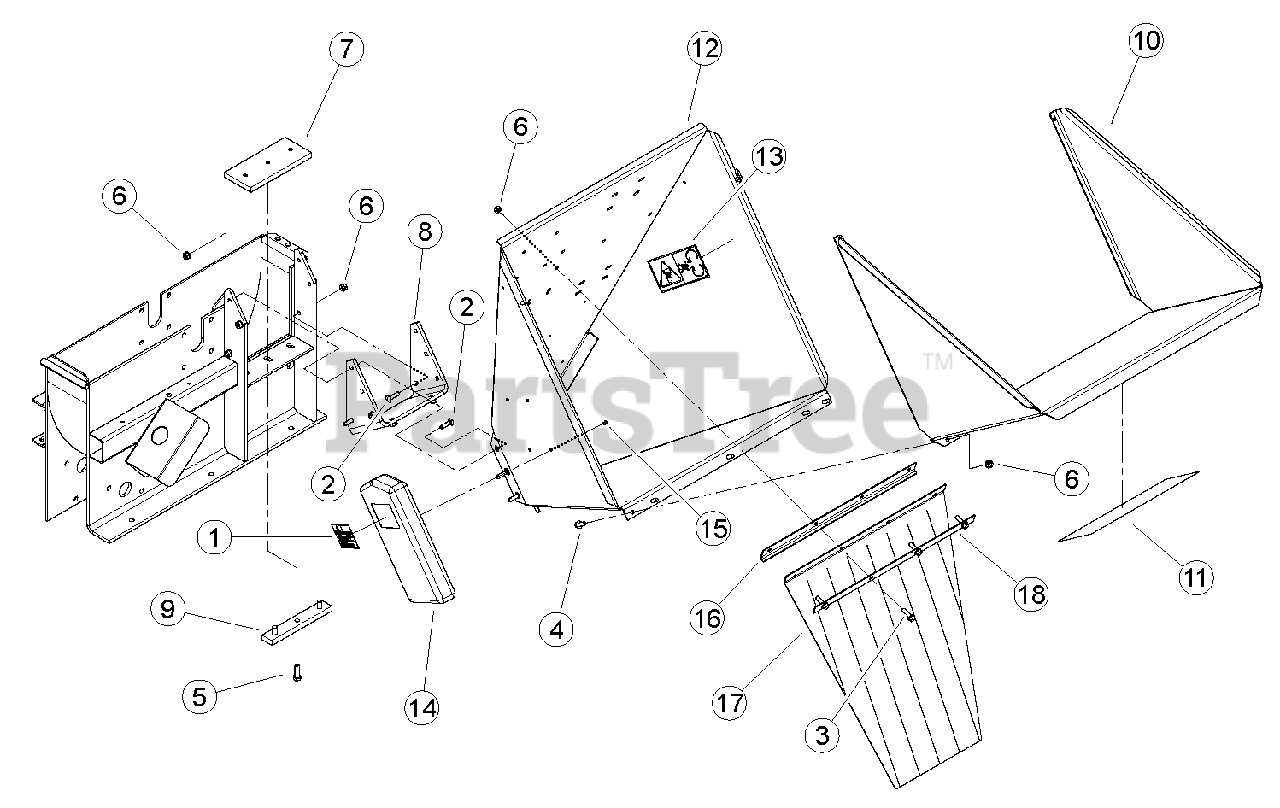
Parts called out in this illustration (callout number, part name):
1	DECAL, MUTILINGUAL MANUAL
2	BOLT, 3/8 X 1-1/2" GR5 NC ZP
3	BOLT, 3/8 X 1-1/4 FLANGE NC
4	BOLT, 3/8 X 1 FLANGE NC
5	BOLT, 1/2 X 1-1/2 GR8 NC ZP HEX HD
6	NUT, 3/8-16 NYLOCK FLANGE
7	PLATE, CHIPPER BOTTOM
8	BASE, CHIPPER CHUTE
9	SPACER, CHIPPER ANVIL
10	ASSEMBLY, CHUTE EXTENSION (CE COMPLIANT ONLY)
11	DECAL, BEARCAT WEB
12	ASSEMBLY, CHIPPER CHUTE
13	DECAL, BLADE DANGER ISO
14	CONTAINER, INSTR. MANUAL
15	RIVET, 1/4 X 1/2 DOME HD BLIND SS
16	ANGLE, FLAP ANCHOR
17	FLAP, CHIPPER CHUTE
18	STRIP, FLAP RETAINER
